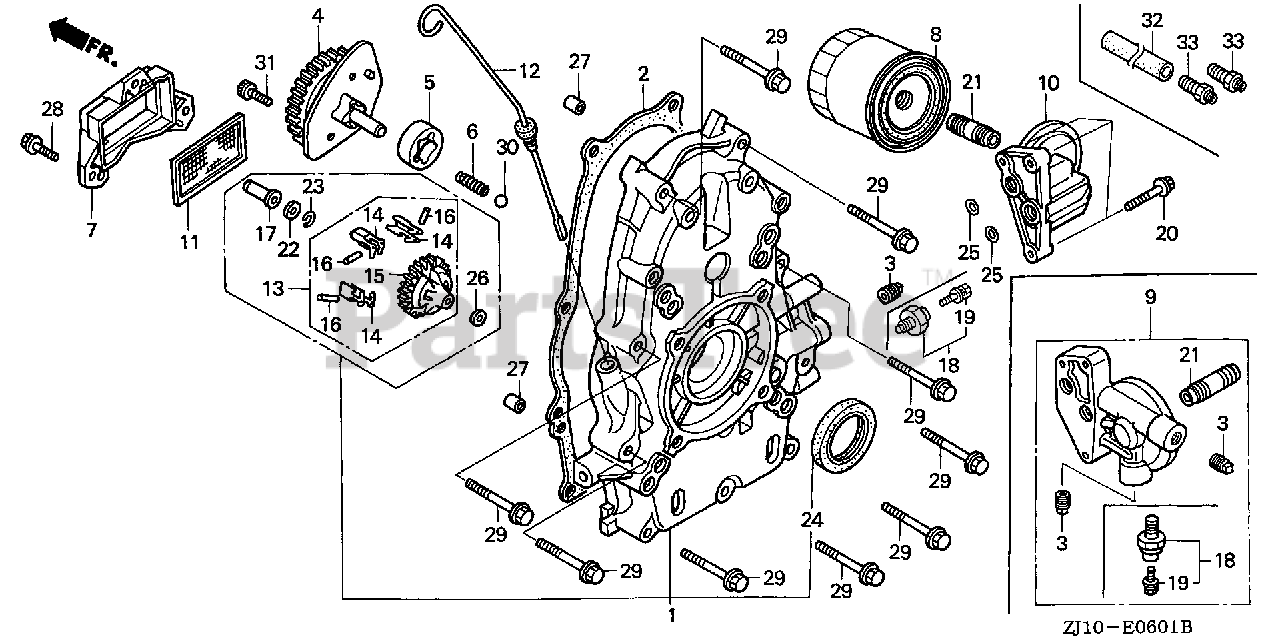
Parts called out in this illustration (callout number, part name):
1	COVER ASSY., CRANKCASE
2	GASKET, CASE COVER
3	BOLT, SEALING
4	COVER ASSY., OIL PUMP (THREE BOLTS)
5	ROTOR, OIL PUMP (OUTER)
6	SPRING, RELIEF VALVE
7	COVER, OIL FILTER
8	FILTER, OIL (FILTECH TOYO ROKI) (SOLD INDIVIDUALLY)
8	FILTER, OIL (TOYO ROKI) (SOLD INDIVIDUALLY)
10	BASE, OIL FILTER
11	SCREEN, OIL FILTER
12	DIPSTICK, OIL
13	GOVERNOR ASSY.
14	WEIGHT, GOVERNOR
15	HOLDER, GOVERNOR WEIGHT
16	PIN, GOVERNOR WEIGHT
17	SLIDER, GOVERNOR
20	BOLT, FLANGE (6X28) (CT200)
21	HOLDER, OIL FILTER
22	WASHER (6X16)
23	CLIP, GOVERNOR HOLDER
24	OIL SEAL (38X58X9)
25	O-RING (11.8X2.4)
26	WASHER, PLAIN (6MM)
27	PIN, DOWEL (8X14)
28	BOLT, FLANGE (6X20)
29	BOLT, FLANGE (8X50)
30	BALL, STEEL (#12) (3/8)
